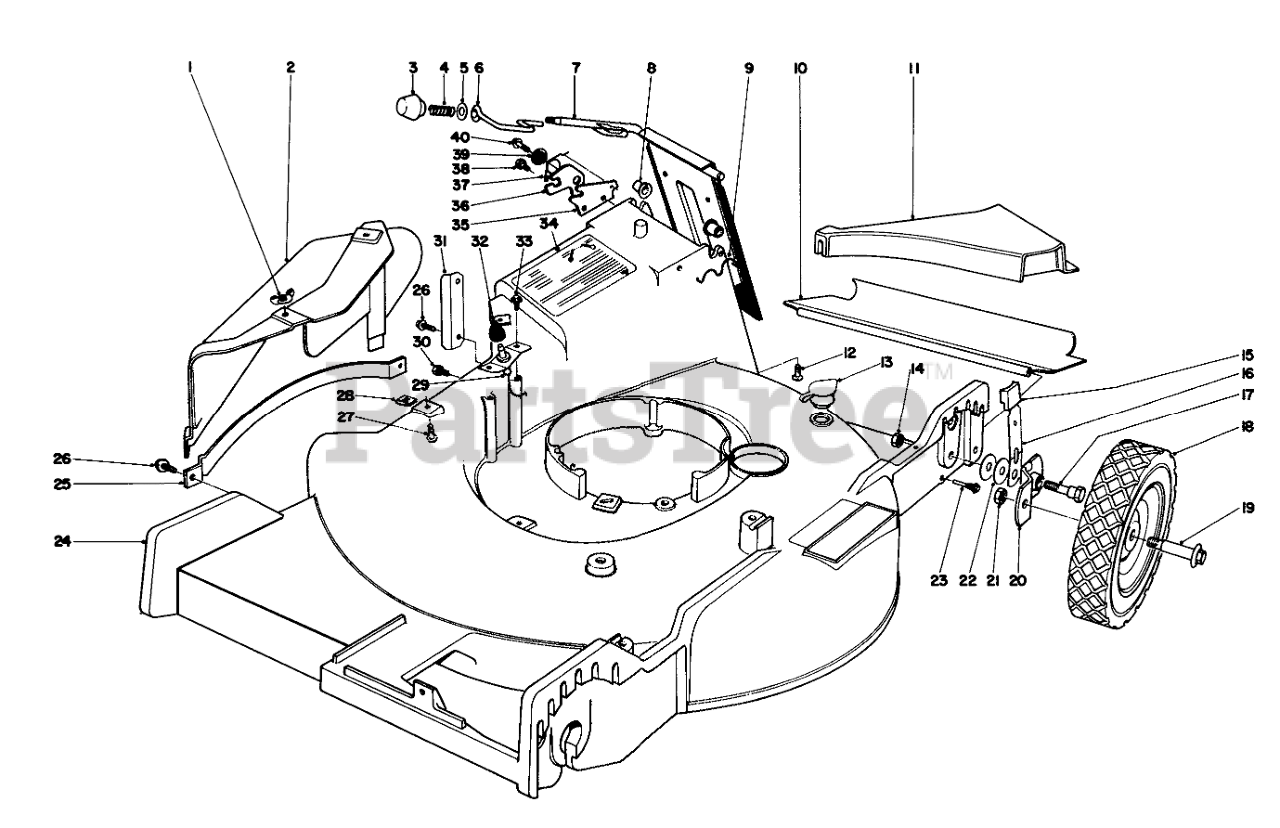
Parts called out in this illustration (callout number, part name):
1	NUT-WING SPECL
2	DEFLECTOR
4	COMPRESSION SPRING
5	WASHER
6	DOOR LATCH
7	Door Handle
8	BUSHING-NYLON
9	Door Retainer
10	REAR SAFETY SHIELD
11	REAR INSERT
12	SCREW-HH
13	WASHOUT PLUG
14	Nut
15	Knob
16	SPRING ARM ASM
17	PIVOT SCREW
18	Wheel Assembly
20	PIVOT ARM ASM A
21	Nut
22	WASHER-PIVOT
23	SAFTEY SHIELD SCREW
24	Housing
25	Bar Safety
26	SCREW
29	Deflector Switch (Incl. Ref. #32)
30	SCREW THD 1/4 20 5/8
31	Clip Retaining
32	Boot Switch
34	Decal-Caution
35	DOOR LATCH PLATE
36	Latch Safety
37	TORSION SPRING
38	SCREW-HWH
39	Latch Spacer
40	Screw
